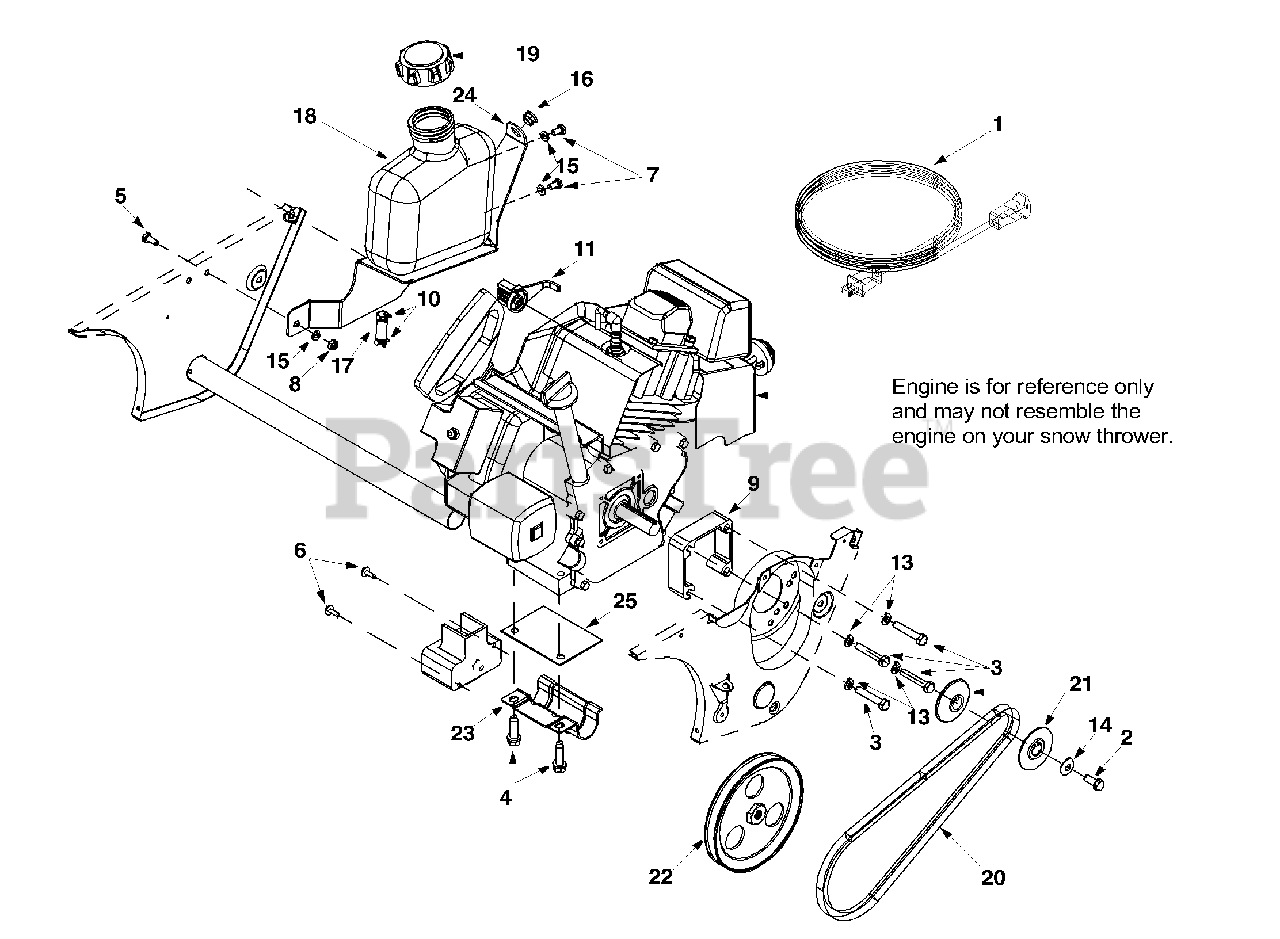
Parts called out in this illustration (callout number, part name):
1	Extension Cord
2	Hex Bolt 5/16-24 x 0.75"
3	Hex Bolt 5/16-24 x 1.75"
4	TT Sems Screw
5	Hex Screw 1/4-20 x 0.620"
6	B Screw #10-16 x 0.625"
7	Hex Screw 1/4-20 x 0.50"
8	Hex Nut 1/4-20
10	Hose Clamp
11	Choke Knob
13	Lock Washer
14	Beleville Washer
15	Lock Washer
16	Plastic Bushing
17	Fuel Line Hose
18	Gas Tank
19	Fuel Cap
20	V-Belt
21	V-Pulley Half
